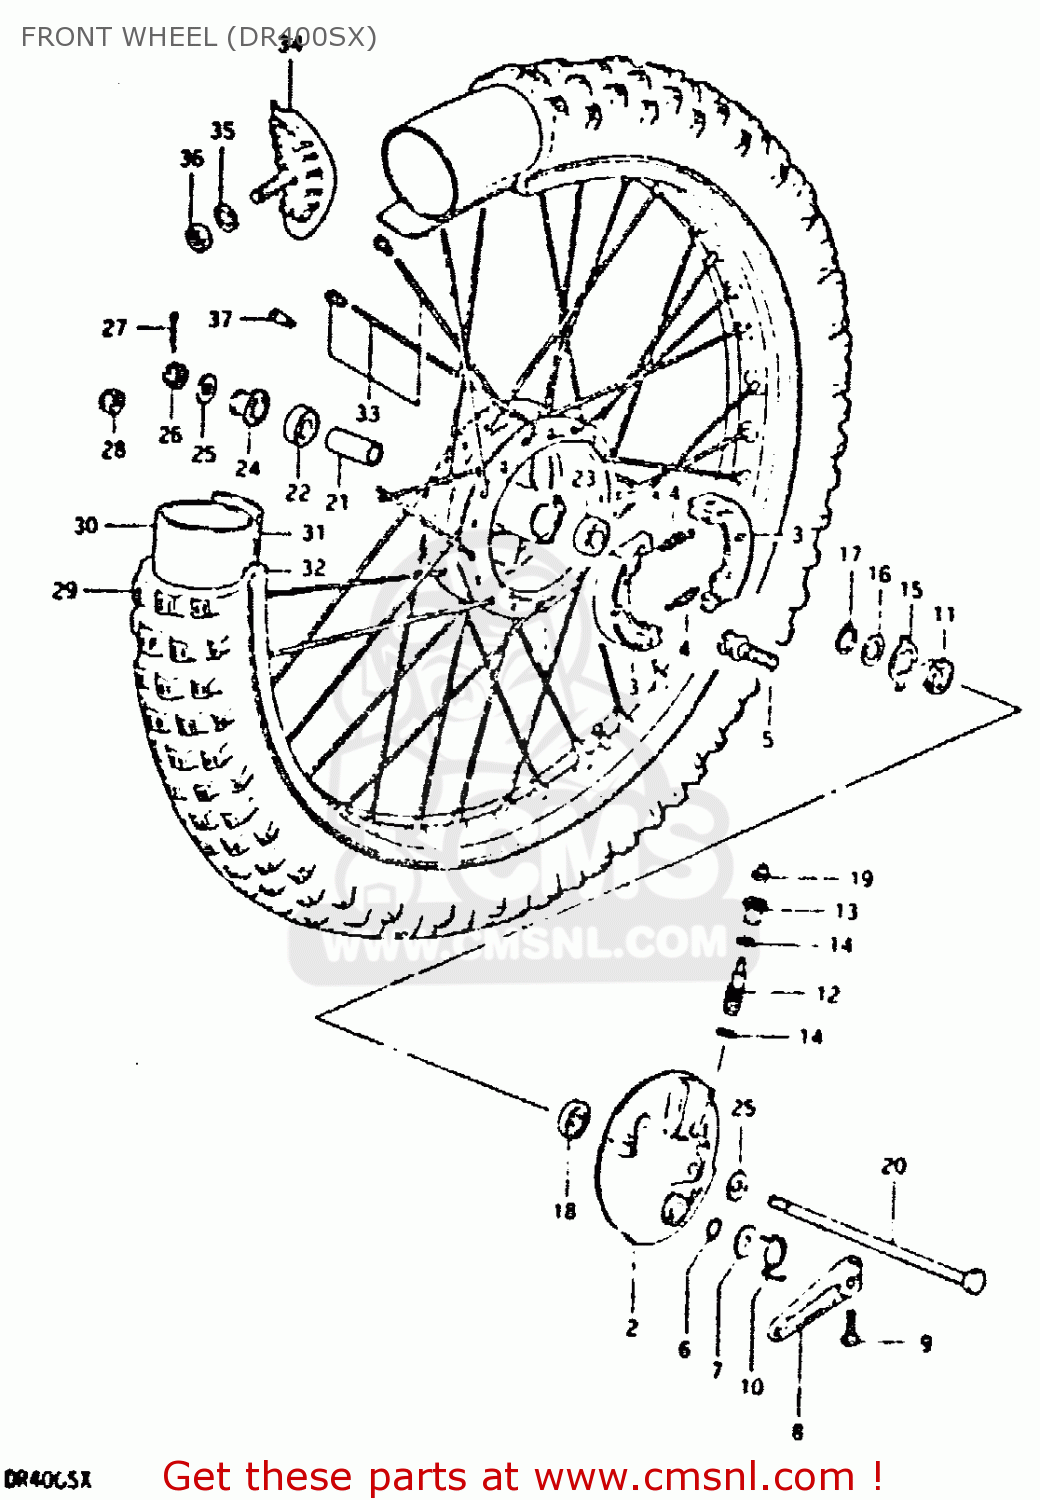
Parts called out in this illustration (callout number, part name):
1	DRUM,FRONT HUB
2	PANEL,FRONT BRAKE
3	SHOE,BRAKE (MCA)
4	SPRING
5	CAM,FRONT BRAKE
6	O-RING,BOSS
7	WASHER (15X24X1.6)
8	LEVER,FRONT BRAKE CAM
9	BOLT
10	SPRING
11	GEAR,SPEEDOMETER
12	PINION,SPEEDOMETER
13	BUSHING,SPEEDOMETER PINION
14	WASHER (5.1X9X0.4)
15	DRIVER,SPEEDOMETER GEAR
16	WASHER(22.5X27X1)
17	CIRCLIP
18	SEAL,OIL(26X38X4)
19	SEAL,OIL(6X10X3)
20	AXLE,REAR
21	SPACER (12.6X19X52)
22	BEARING, RH
23	BEARING
24	SPACER,FRONT AXLE,RIGHT
25	WASHER
26	NUT, REAR AXLE
27	COTTER PIN
29	TIRE,FRONT
30	TUBE
31	PROTECTOR,WHEEL,INNER
32	RIM,FRONT WHEEL
33	SPOKE SET,FRONT
34	STOPPER,BEAD
35	WASHER
36	NUT
37	BALANCER,WHEEL (50G)
